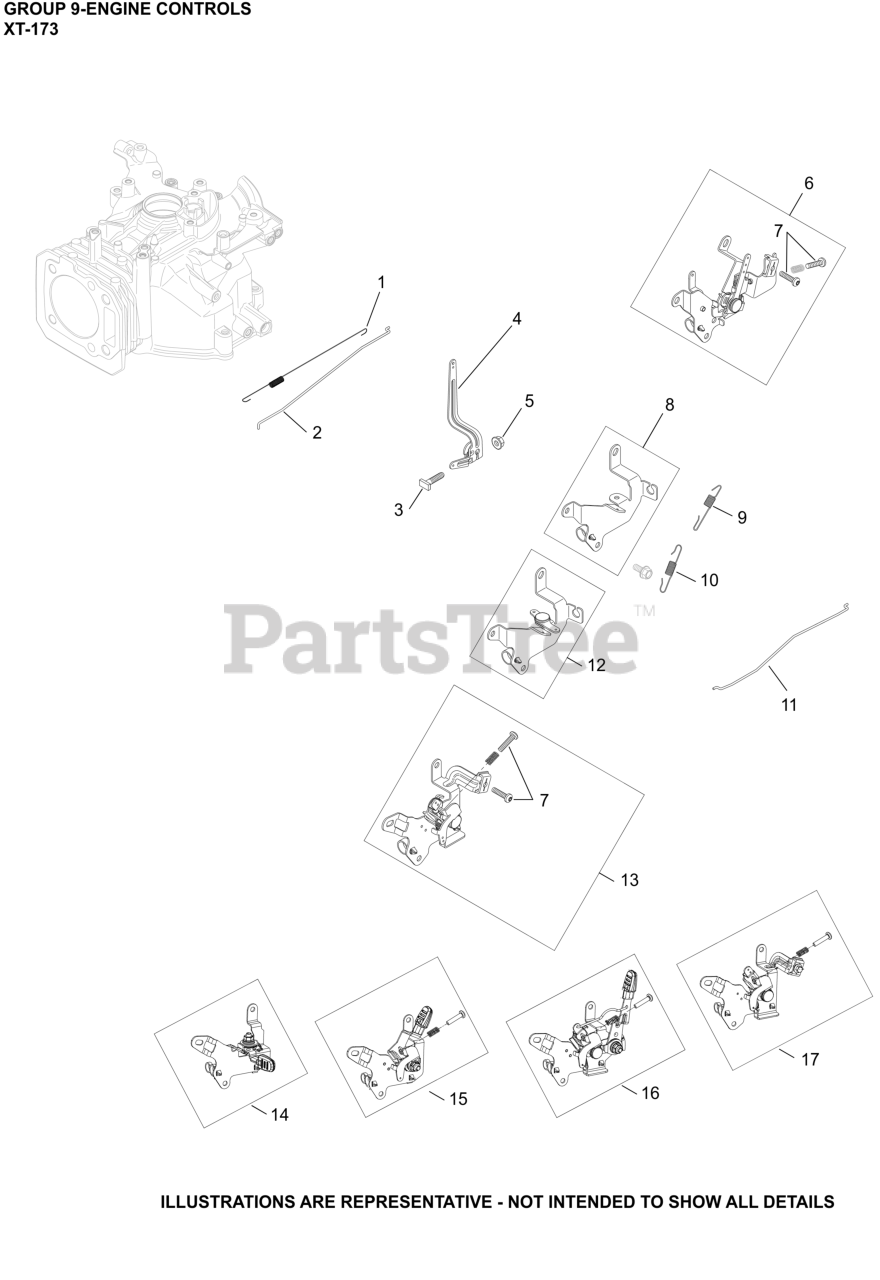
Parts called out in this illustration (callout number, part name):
1	SPRING, LINKAGE-(#DSC)
2	LINKAGE, GOVERNOR
3	SCREW, RECTANGLE HEAD (M6)
4	LEVER, GOVERNOR-USE 14 090 37-S
10	SPRING, GOV (2800-3300 RPM)
11	LINKAGE, CHOKE
13	CONTRL ASSY (VAR. SPEED)-(#1453618S)
NI	SCREW, (M5) HEX FLANGE
